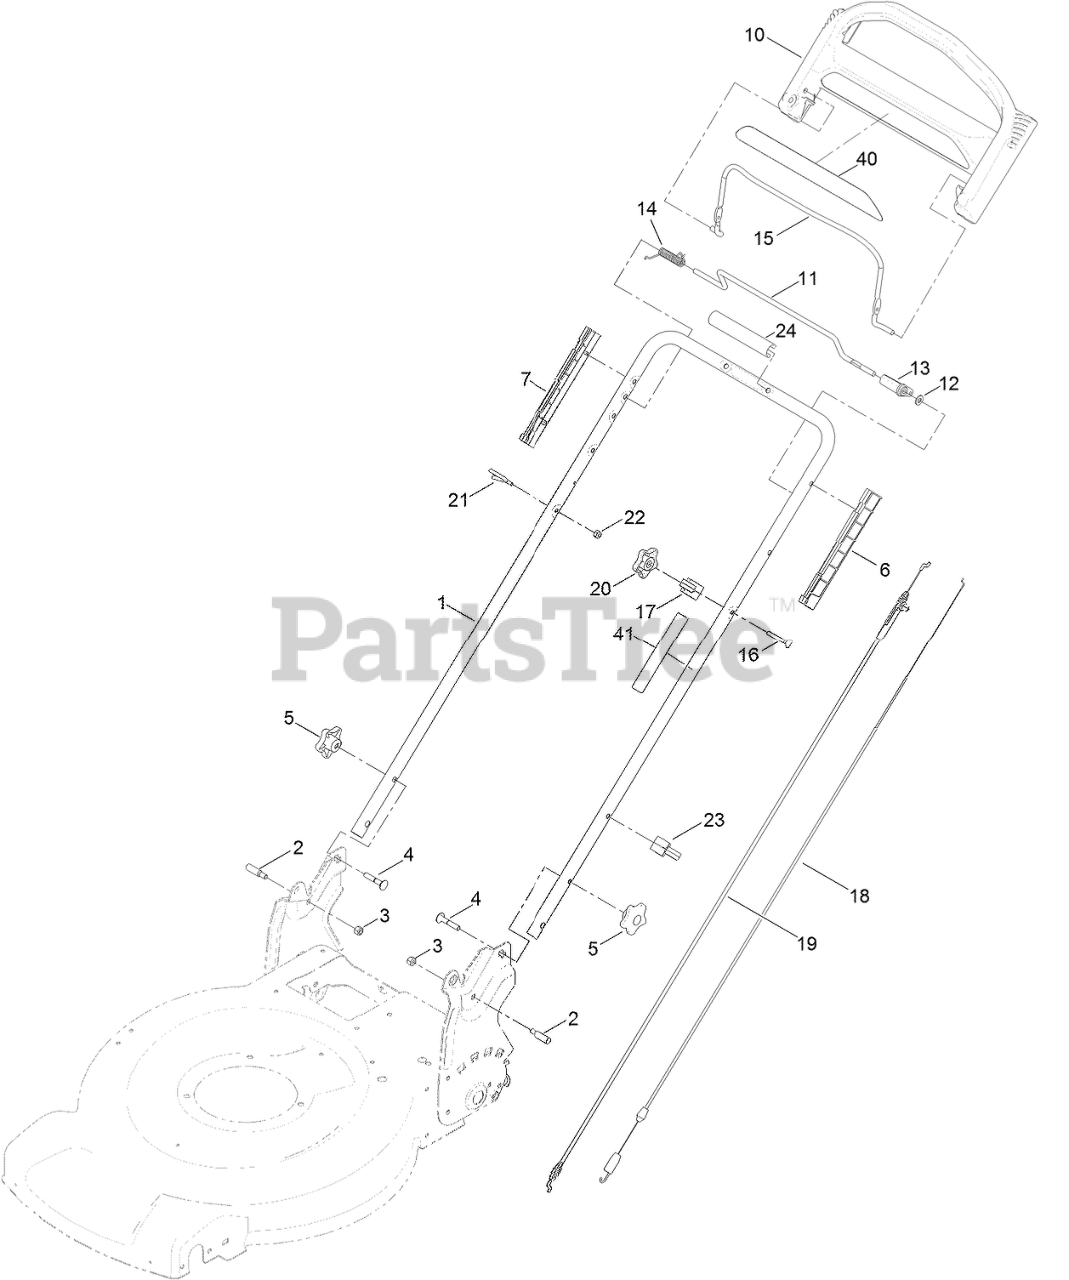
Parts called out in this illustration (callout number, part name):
2	BOLT-SHOULDER
3	NUT-LOCK, NI
4	SCREW-CARR
5	KNOB-HANDLE
6	GUIDE-LH
7	GUIDE-RH
10	HANDLE-CONTROL
11	BAR-CONTROL, TRACTION
12	WASHER-PLAIN
13	LEVER-TRACTION
14	Spring-Torsion
15	BAIL-BRAKE
16	SCREW
17	ANCHOR-CABLE
18	CABLE-TRACTION
19	CABLE-BRAKE
20	KNOB-HANDLE, LOCKING
21	GUIDE-ROPE
22	NUT-LOCK, NI
23	GUIDE-CABLE
24	HANDLE-COVER
40	DECAL-HANDLE
41	DECAL-TRACTION, ADJUST
